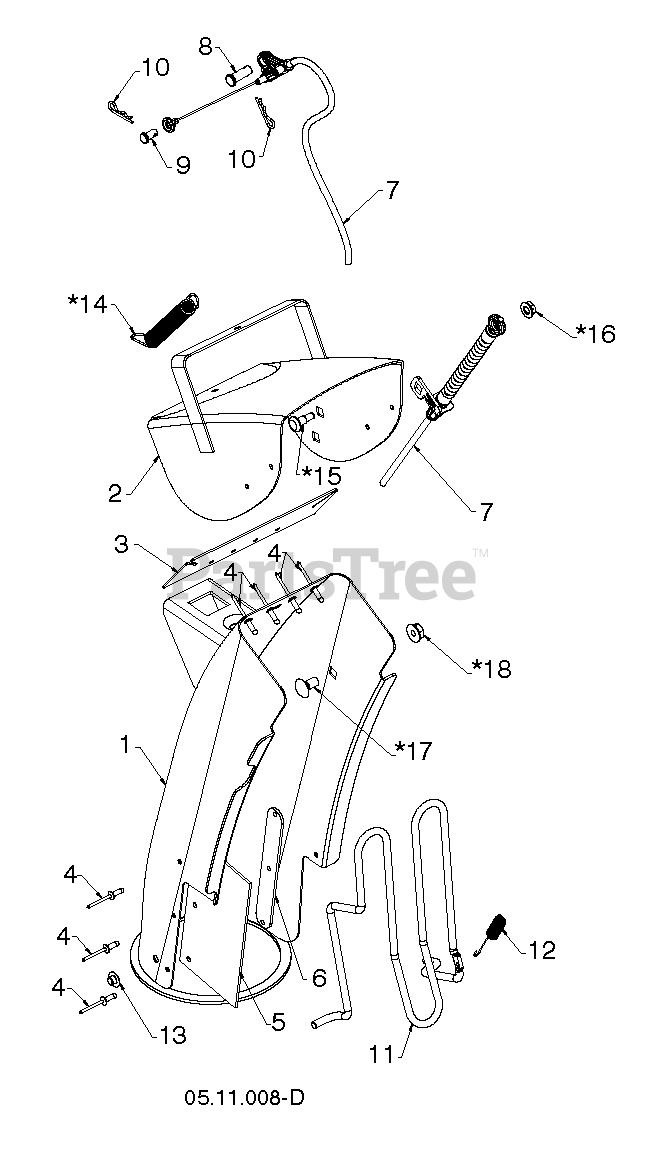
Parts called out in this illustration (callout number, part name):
1	DEFLECTOR.WELDMENT.RED
7	Deflector Chute Control Cable
8	Clevis Pin, 5/16 X .875
9	Clevis Pin, .25 X .31
10	Hair Pin, .059 X 1.125
14	SPRING
15	Carriage Bolt, 5/16-18 X 5/8 Black
16	Flange Hex Lock Nut, 1/4-20 Large
17	Carriage Bolt, 5/16-18 X 5/8 Black
18	LOCKNUT-FLANGE 5/16-18
